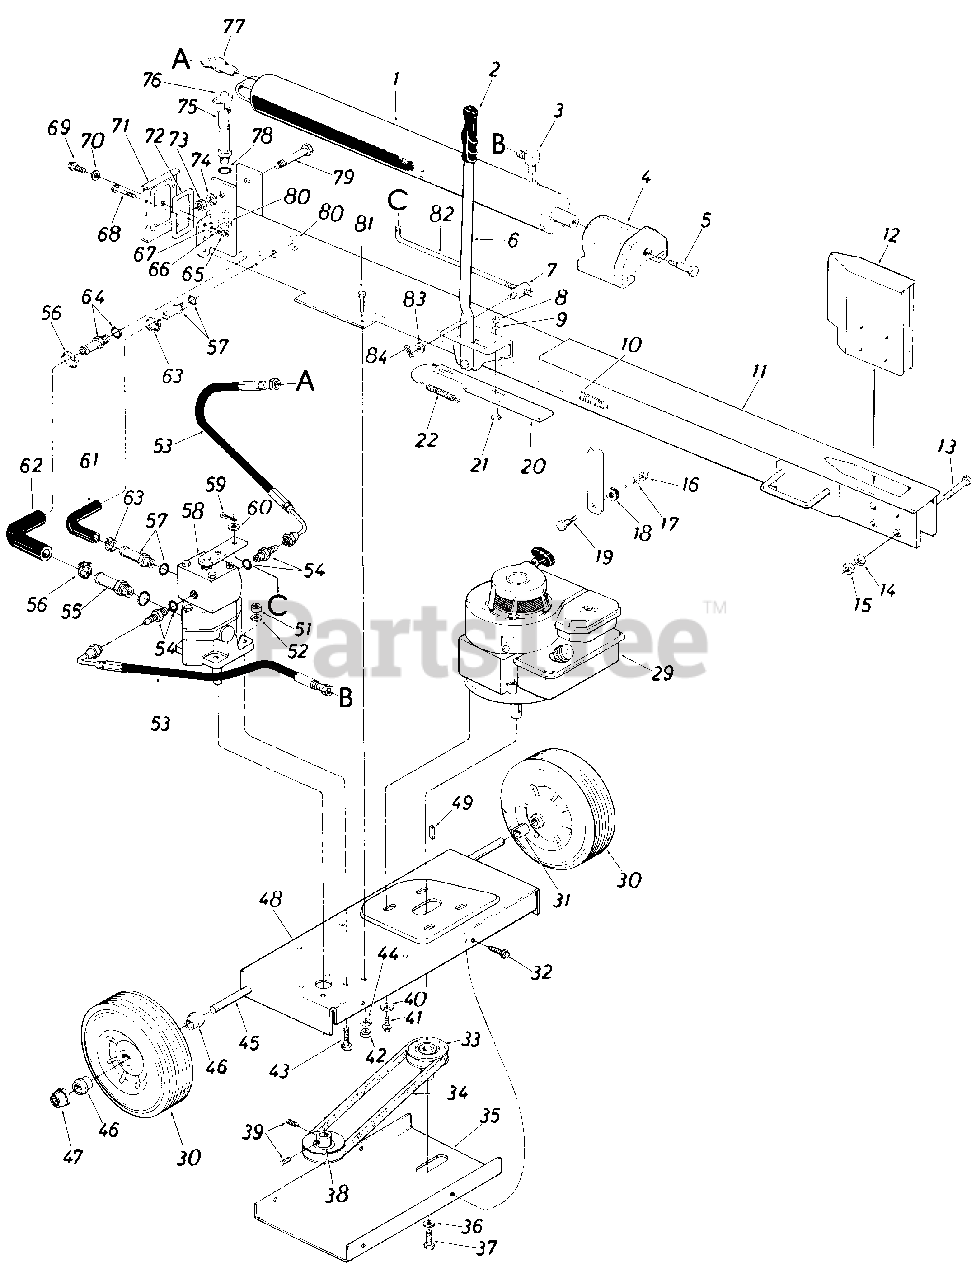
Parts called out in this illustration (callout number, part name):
1	2-1/2" Cylinder Ass'y. Comp.
2	Grip
3	90ø Elbow Adapter
4	Pusher Plate
5	Shoulder Bolt 5/8" Dia. x .660" Lg. 1/2-13 Thd.
6	Engagement Handle
7	Adjustment Ferrule
8	Hex Nut 5/16-18 Thd.
9	L. Wash 5/16" I.D.
10	Strainer Tube Ass'y.
11	Oil Tank Ass'y. Comp
12	Wedge Ass'y.
13	Hex Bolt 5/8-18 x 3.50" Lg. (Grade 5)
14	L.-Wash. 5/8" I.D.
15	Hex Nut 5/8-18 Thd.
16	Hex Nut 3/8-16 Thd.
17	L.-Wash. 3/8" I.D.
18	Rubber Wash.
19	Shoulder Bolt .498 x .340
20	Engagement Brkt.
21	Shoulder Bolt .437" Dia. x .180" Lg.
22	Extension Spring .50" O.D. x 4.25" Lg.
29	Engine - B & S
30	Wheel Ass'y. Comp. 10.0" x 2.75
31	Sleeve .532" i.D. x 875" O.D. x .90" Lg.
32	Hex Wash. Hd. Self Tap. Scr. 1/4- 20 x . 50 " Lg.
33	1/2" V-Pulley 7/8" I.D. x 7/8" I.D. x 3-1/4" O.D.
34	"V"-Belt (4L) 1/2" V x 30" Lg.
35	Belt Cover
36	L.-Wash. 5/16" I.D.
37	Hex Bolt 3/8-24 x 1.0" Lg.
38	1/2 (4L) "V"-Pulley 5/8" I.D. x 3-1/2" O.D.
39	Set Scr. 1/4-28 x .25" Lg.
40	Bell.-Wash..40" I.D. x.88" 0. D.
41	Hex Wash. Hd. TT-Tap Scr. 3/8-16 x .87" Lg.
42	Hex Nut5/16-24 Thd.
43	Hex Bolt 5/16-18 x 1.00" Lg.
44	L.-Wash. 5/16" I.D."
45	Axle Shaft 5/8" Dia. x 25.5" Lg.
46	FlangeBrg w/Flats.631" 1 b
47	Push Cap 5/8" Dia. Rod
48	Frame- Engine
49	Sq. Key 3/16" x 3/16" x 1.50" Lg.
51	Hex Nut 5/16-18 Thd.
52	L.-Wash. 5/16" I.D.
53	High Pressure Hose
54	Adapter - or Boss to MJIC 9/16-18 to 7/16-20
55	Adapter 3/4" Tubing to 3/4 -16 M-Boss
56	Hose Clamp 5/8" I.D.
57	Adapter 1/2" Tube 9/16-18 or M-Boss
58	Valve Ass'y.
59	Cotter Pin 3/32" Dia. x .75" Lg.
60	Fl.-Wash. 344" I.D. x .62" O.D. x .063
61	Return Hose .50" I.D.
62	Suction Hose .75" I.D.
63	Hose Clamp 1/4" I.D.
64	Adapter 1.0" Tube 1-1/16- 12 "O"-Ring
65	Hex Nut 5/16-18 Thd.
66	L.-Wash. 5/16" I.D.
67	Fl.-Wash. .343" I.D. x .687" O.D. x .062
68	Hex Bolt 5/16-18 x 1.50" Lg.
69	Hex Hd. Tap Scr. 5/16"
70	Gasket
71	End Plate
72	Gasket
73	Hex Nut 3/4" Thd.
74	L.-Wash. 3/4." I.D.
75	Filler Tube Ass y.
76	Oil Fill Cap
77	45ø Male Adapter 7/16-20 MJ-1/4-18 NP
78	"O"-Ring .92" I.D. x 1.16" O.D. x .116 Dia.
79	Hex Bolt 3/4" x 4.0" Lg.
80	Hex Nut 11/16-12 Thd.
81	Hex Bolt 5/16-24 x 1.00" Lg. (Grade 5)
82	Engagement Rod 16.75" Lg.
83	Fl.-Wash. .344" I.D. x.62" O.D. x .063
84	Hair Pin Cotter 5/16" Dia.
